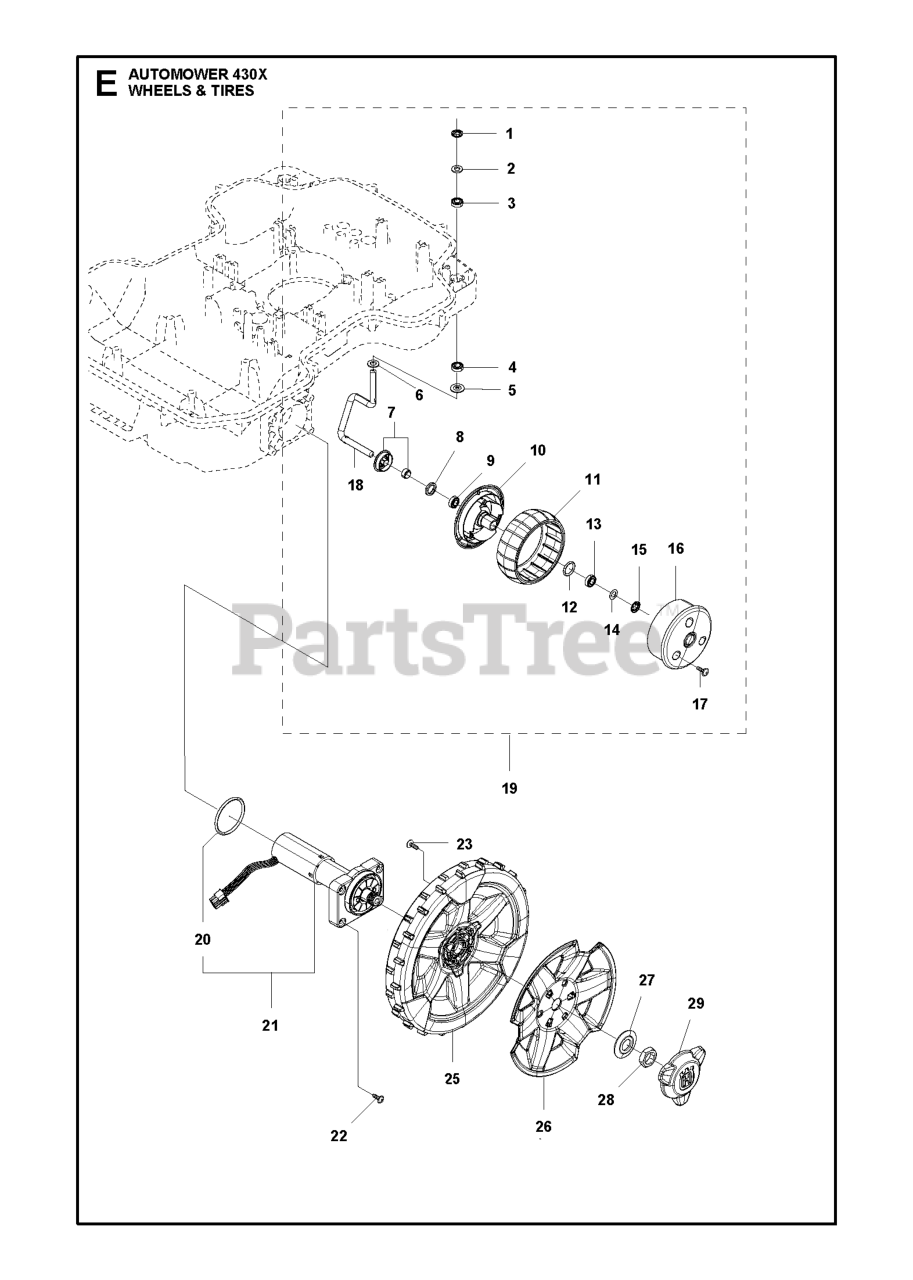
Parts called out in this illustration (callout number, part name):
1	LOCKWASHER PUSH-ON TYPE P 8 BV
2	WASHER DIN 988 13X8X0.5
3	BALL BEARING SINGLE ROW S688
4	BALL BEARING SINGLE ROW S688
5	WASHER FRONT WHEEL CENTER HOLE
6	WASHER DIN 988 13X8X0.5
7	SHIELD KIT
8	SEALING 12X18X3
9	BALL BEARING SINGLE ROW S688
10	WHEEL FRONT WHEEL INSIDE
11	WHEEL RUBBER TYRE
12	O-RING 2,62X15,54
13	BALL BEARING SINGLE ROW S688
14	WASHER DIN 988 13X8X0.5
15	LOCKWASHER PUSH-ON TYPE P 8 BV
16	WHEEL FRONT WHEEL OUTSIDE
17	SCREW 14MM
18	SPINDLE SPINDLE FRONT WHEEL RI
19	WHEEL KIT FRONT
20	O-RING LIGHT GREY
22	SCREW ITXPANT
23	SCREW 14MM
26	WHEEL COVER REAR WHEEL
27	WASHER WASHER REAR WHEEL 16X40
28	HEXAGON THIN NUT
29	HUB CAP REAR WHEEL NO CENTER P
